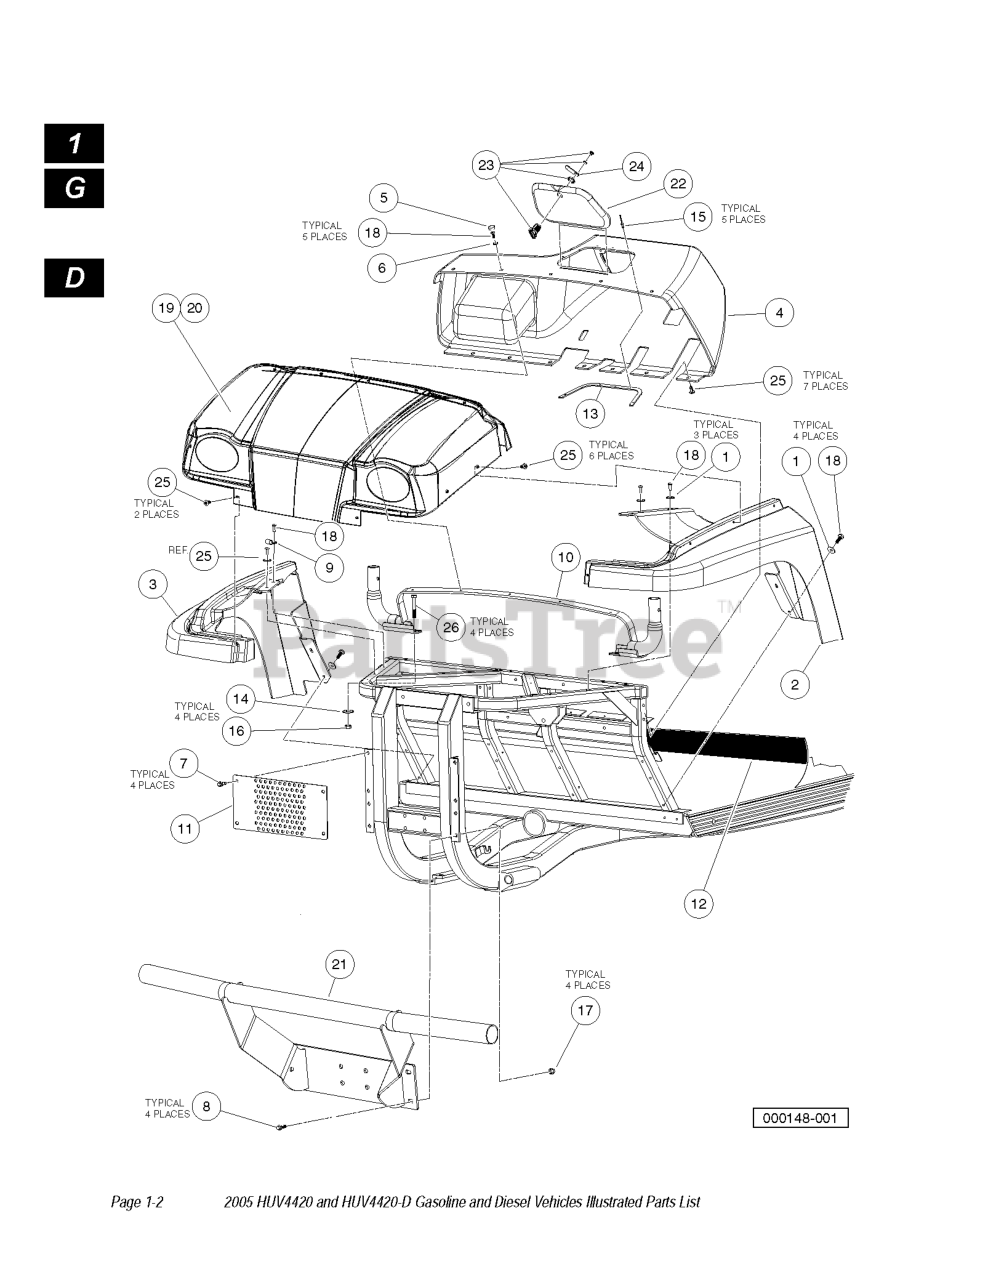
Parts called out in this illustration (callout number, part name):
2	FENDER, LEFT FRONT B
3	FENDER - RIGHT FRONT B
4	DASH BOARD WITH ACCESS HOLE
5	CAP 1/4" PLASTIC SCREW HEAD
6	WASHER 1/4 ID SCALLOPED PLAST
7	SCREW, M8 X 1.25 X 30 TRI, BLK
8	BOLT - FLANGED HD, M8 X 30.0
9	P-CLAMP, INSULATED .312 IN
10	WELDMENT, SUPP, COWL, ROPS
11	GRILL, FLAT
12	MAT, FLOOR AWD
13	SUPPORT, ACCESS PANEL, DASH
14	WASHER HARD, M10
15	RIVET, .125" DIA, .311" PANEL
16	NUT FLG M10 X 1.5 MECH DEF
17	LOCK NUT, FLG M8 X 1.25 NYLON
18	SCREW, 1/4-20X1.0 PN HD TORX
19	Cowl, Camo
20	COWL, OEM, ORANGE
21	Brush Guard
22	PANEL, ACCESS, DASH
23	CAM LOCK BODY
24	LATCH, CAM, ACCESS PANEL
25	SCREW, TUFLOK PANEL, 1/4
26	BOLT, M10 X 1.50 X 65
